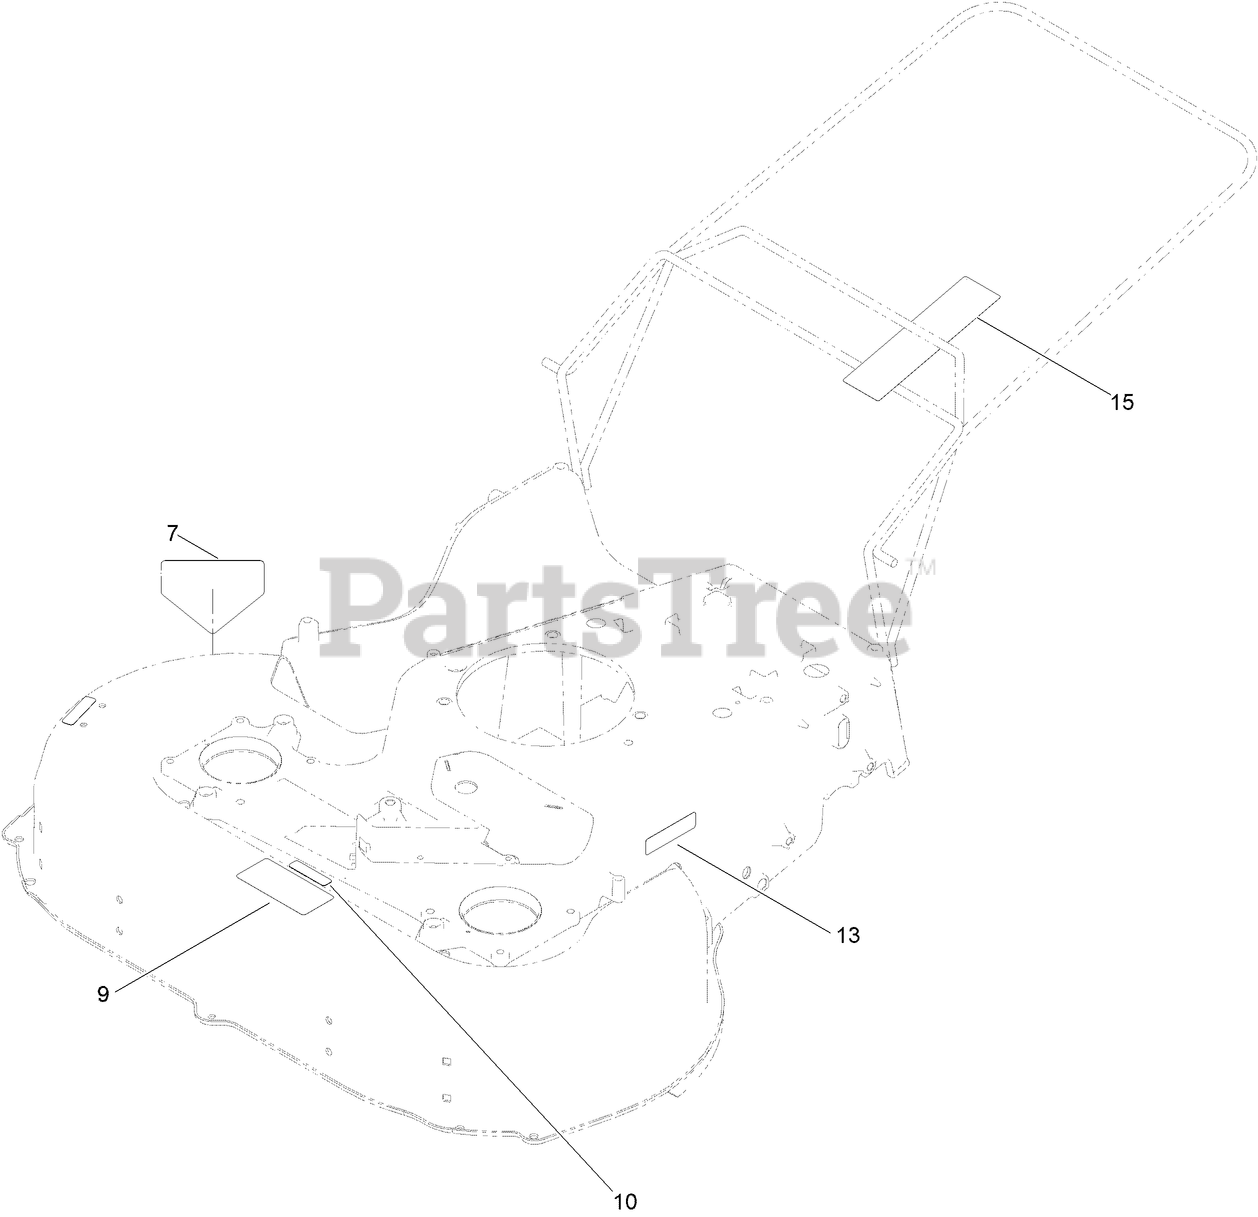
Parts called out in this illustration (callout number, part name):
7	DECAL-DANGER
10	DECAL-WARNING
13	DECAL-PROP 65, SHORT, TRILINGUAL
15	DECAL-WARNING (BAG)
